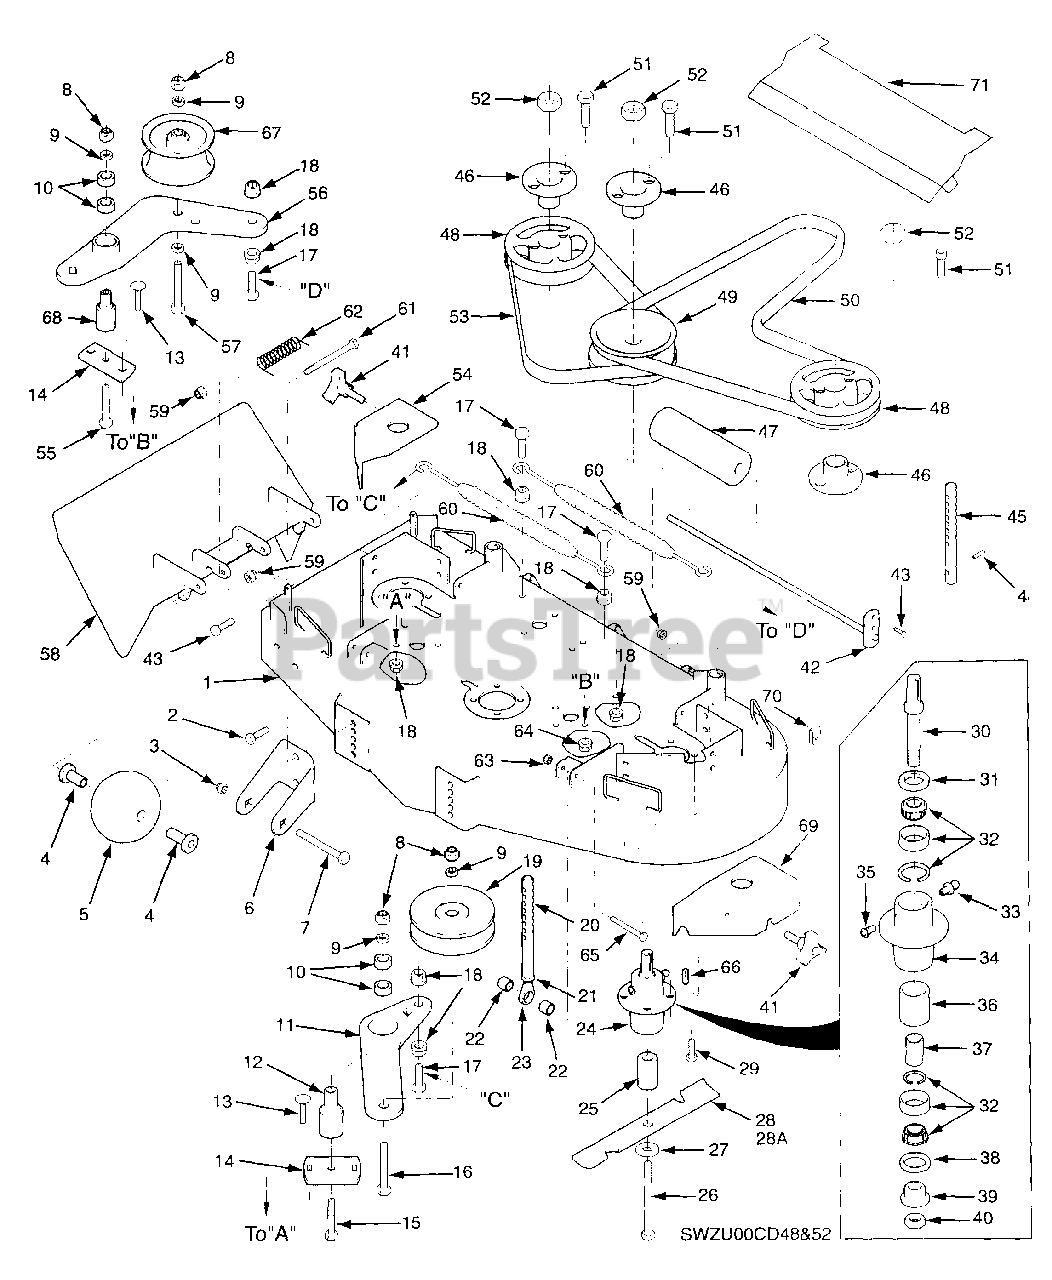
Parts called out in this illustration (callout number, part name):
1	Cutter Deck with Decals
2	Capscrew, 3/8-16 x 1.0" Serr. Fig.
3	Lock Nut, 3/8-16 Center Lock
4	Bushing, 376 ID Oilite
5	Wheel, Anti-Scalp
6	Bracket, Anti-Scalp Wheel
7	Bolt, Carriage 3/8-16 x 4.0"
8	Hex Nut, 3/8-16 Elastic Stop
9	Flatwasher, 3/8 (.938 x .391 x .105)
10	Ball Bearings
11	Idler Arm RH
12	Pivot, Idle - Short
13	Bolt, Carriage 5/16-18 x 1.0"
14	Base, Idler Pivot
15	Capscrew, Hex Head 3/8-16 x 2.50"
16	Capscrew, Hex Head 3/8-16 x 2.0"
17	Capscrew, Hex Head 3/8-16 x 1.50"
18	Nut, 3/8-16 Serrated Flange
19	Pulley, Idler
20	Pin Assembly
21	Nut, 3/8-24 Jam
22	Spacer, Deck Adjustment Pin
23	Rod End, Male 3/8-24
24	Spindle Assembly
25	Spacer, Spindle
26	Bolt,Hex Head 5/8-11 x 9.50"
27	Flatwasher, 5/8 W
28	Cutter Blade 16-1/2" (marbane)
28A	Cutter Blade 16-1/2" Hi Lift (marbane)
29	Bolt, Hex Head 5/16-18 x 1.25"
30	Spindle Shaft
31	Seal, Cutter Spindle - Top
32	Tapered Bearings
33	Grease Fitting
34	Spindle Housing
35	Relief Fitting, Cutter Spindle
36	Spacer Outside
37	Spacer, Inside
38	Seal, Cutter Spindle - Bottom
39	Spindle Bushing
40	Nut, Spindle
41	Wing Nut, 3/8-16
42	Roller Shaft
43	Bolt, Hex Head 5/16-18 x 1.0"
44	Pin, Slotted Spring 3/16 x 1.50"
45	Pin, Deck Adjustment Rear
46	Tapered Hub
47	Guide, Roller
48	Pulley
49	Pulley, 5.75 Double Groove
50	Belt, Deck Drive
51	Capscrew, Sckt. Hd. 1/4-20 x 1.375"
52	Hex Nut, 5/8-11
53	Belt, Cutter Deck
54	Belt Cover, RH
55	Capscrew, Hex Head 3/8-16 x 3.25"
56	Idler Arm Weldment
57	Capscrew, Hex Head 3/8-16 x 3.75"
58	Discharge Chute
59	Nut, 5/16-18 Serrated Flange
60	Spring, Deck Idler
61	Bolt, Hex Head 5/16-18 x 4.25"
62	Spring, Chute Return
63	Nut, 3/8-16 Elastic Stop
64	Nut, 5/16-18 Serrated Flange
65	Bolt, Hex Head 3/8-16 x 2.50"
66	Key, 1/4 x 1/4 x 2.0"
67	Pulley, Idler
68	Pivot, Idler - Long
69	Belt Cover LH
70	U-Nut, 3/8-16
71	Heatshield
